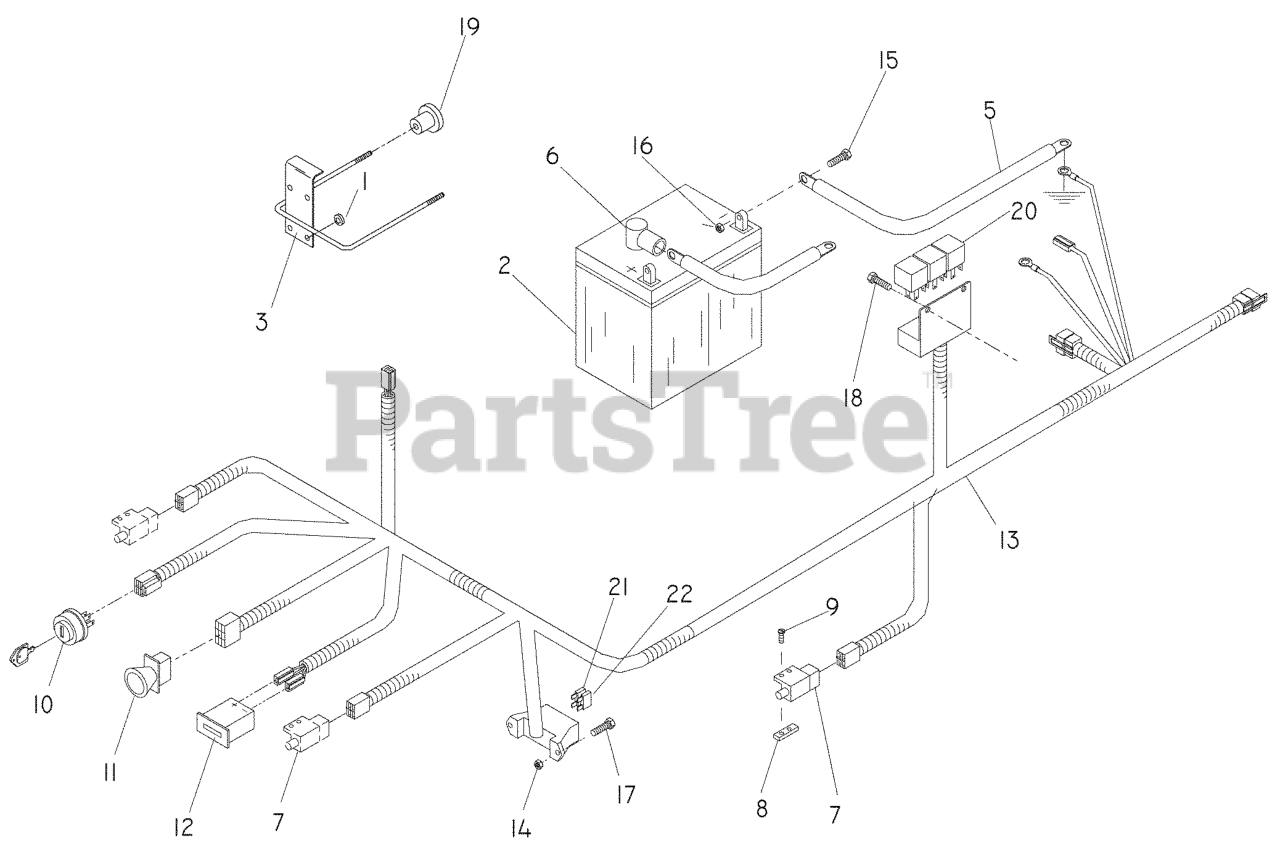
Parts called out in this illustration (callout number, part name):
1	GROMMET, BUMPER
2	BATTERY, 12 V 330 AMP
3	BATTERY HOLD DOWN
4	POST.CABLE LONG
5	CABLE-NEGATIVE
7	SWITCH, INTERLOCK
8	TAPPED PLATE
9	SCREW #10-24 X 5/8
10	RP IGNITION SWITCH
11	SWITCH, PTO 10 AMP
12	HOUR METER
13	FRAME HARNESS
14	NUT 10-24 NYLOC
15	HCS 5/16C X 3/4
16	NUT 5/16 NYLOC
17	SCREW, #1--24 X 1/2 SLOTTED
18	SCREW #10 X 1/2 SELF TAPPING
21	FUSE, 7.5 AMP 32 VOLT ATO
22	FUSE, 20 AMP 32 VOLT ATO
